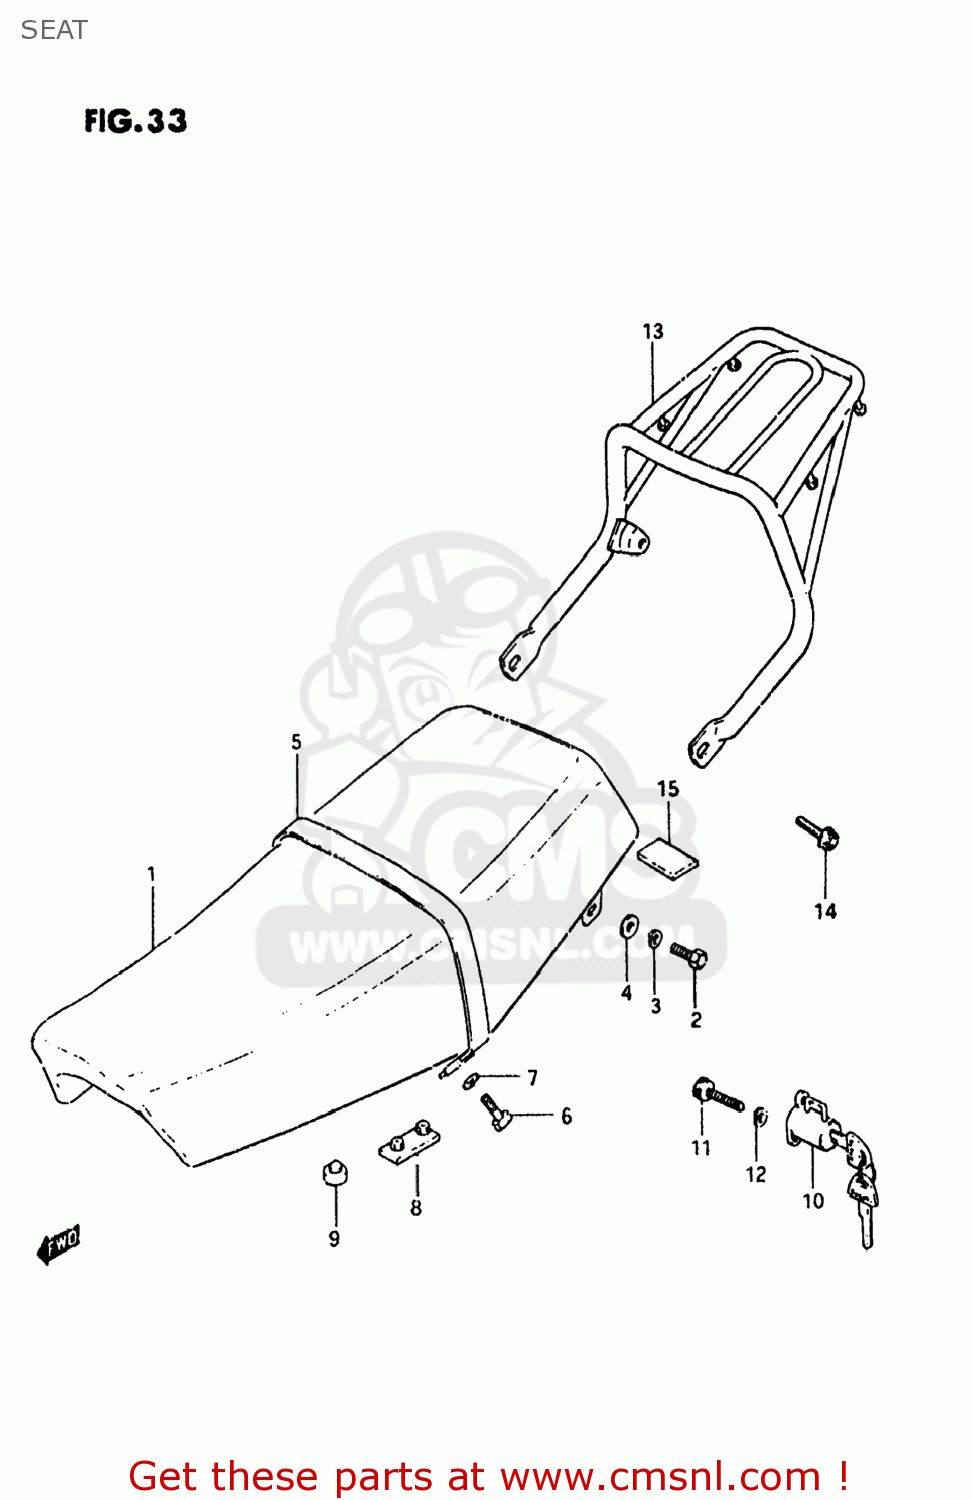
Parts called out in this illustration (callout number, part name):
1	SEAT ASSEMBLY
2	BOLT
3	LOCK WASHER
4	WASHER
5	BAND,SEAT GRIP
6	BOLT
7	LOCK WASHER
8	CUSHION
9	CUSHION
10	LOCK ASSEMBLY,HELMET
11	BOLT 6X11
12	LOCK WASHER
13	CARRIER
14	BOLT
15	TAPE, SEAT UNDER
